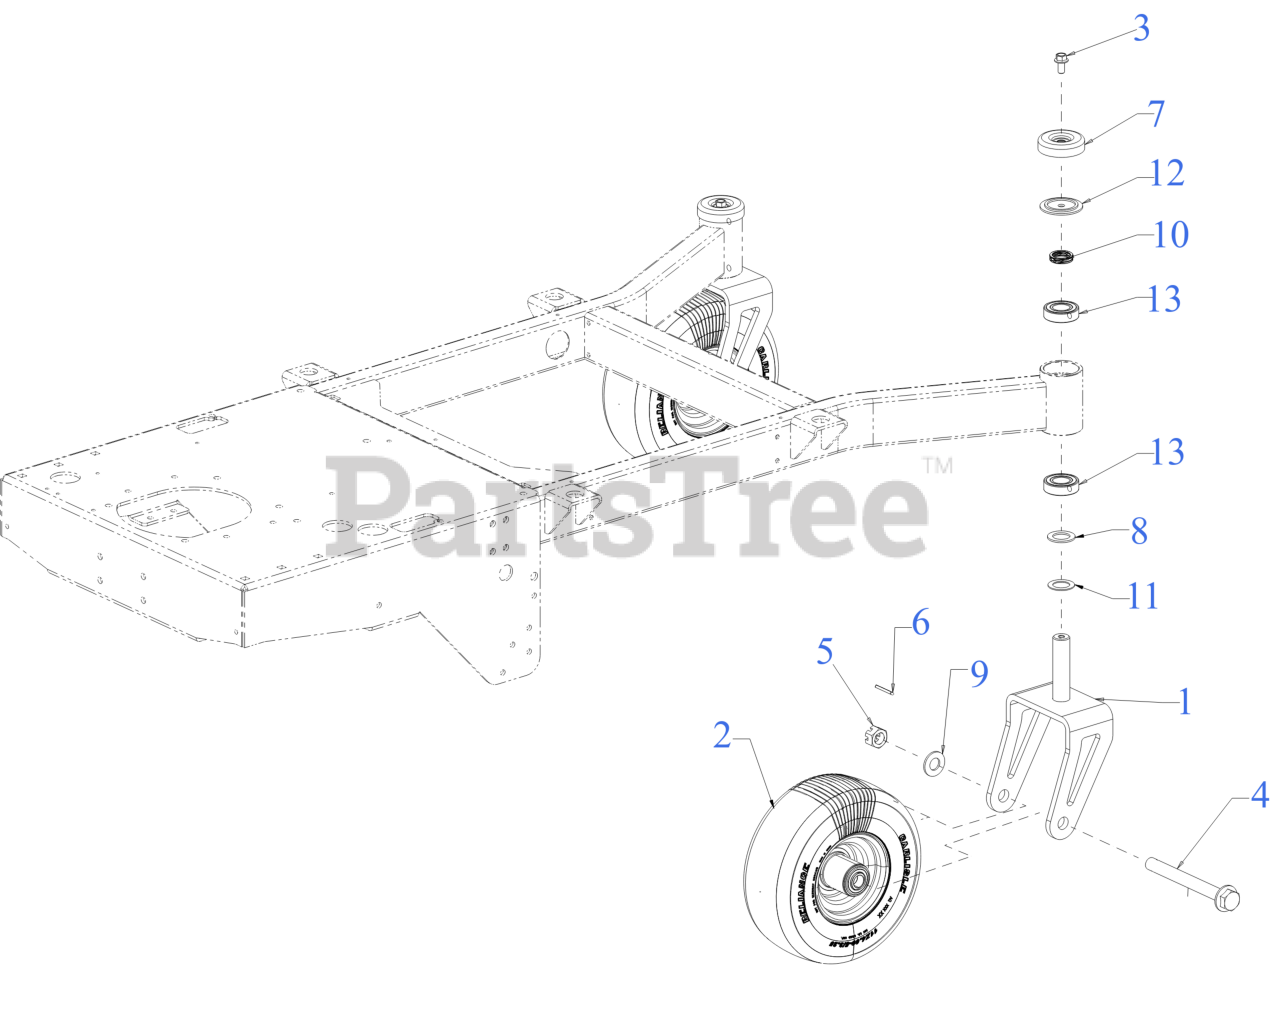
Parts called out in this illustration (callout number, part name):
2	WHEEL ASSEMBLY (11 x 4 - 5 SIMI PNE)
2	SEALED BALL BEARING
3	BOLT - 3/8-16:.75:GR5:PATCH LOCK
4	HEX FLANGE BOLT 3/4-16x7.0 GR5
5	HEX NUT CASTLE 3/4-16
6	COTTER PIN-5/32 DIA
7	AXLE CAP 2.5"
8	FLAT WASHER 1.031 X1.62 X.095
9	FLAT WASHER
10	WAVE WASHER
11	WASHER 1.010X1.560X.060
12	SHOULDER SPACER
13	BALL BEARING (1.0 x 52 x 15)
